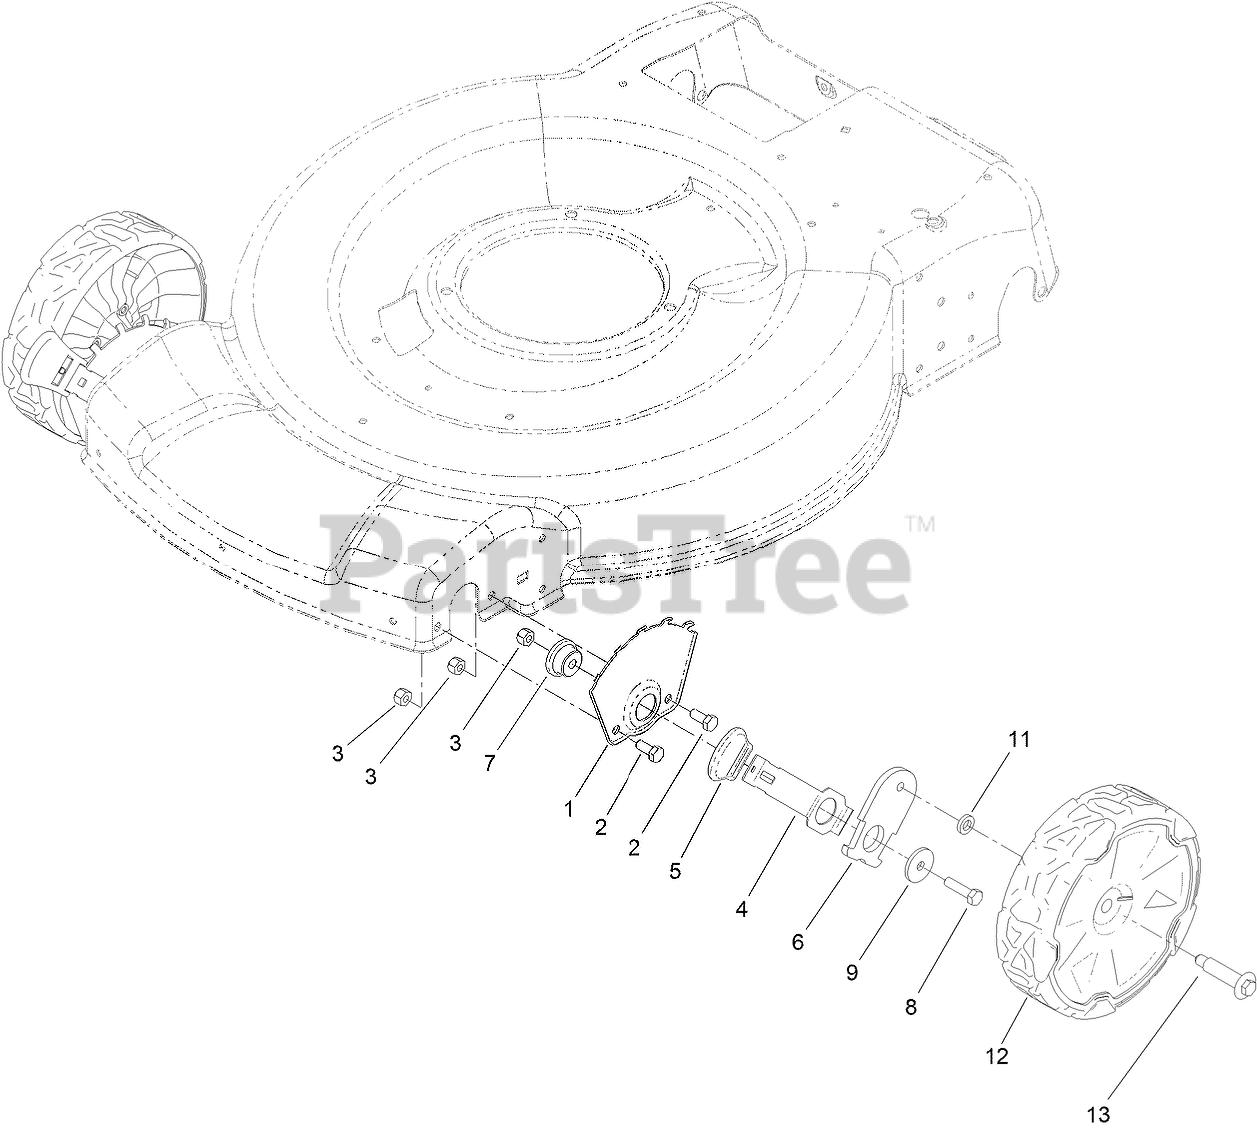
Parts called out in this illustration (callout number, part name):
1	PLATE-HOC,FRONT FSVQ WEDNESDAY
2	SCREW-HH
3	NUT-LOCK, NI
4	ARM-SPRING
5	KNOB-HOC
6	ARM-PIVOT, FRONT
7	BUSHING-MOUNT, HOC
8	SCREW-HH
9	WASHER-FLAT
11	WASHER-WHEEL BOLT
12	ASM-8" WHEEL, IDLER
13	WHEEL BOLT
